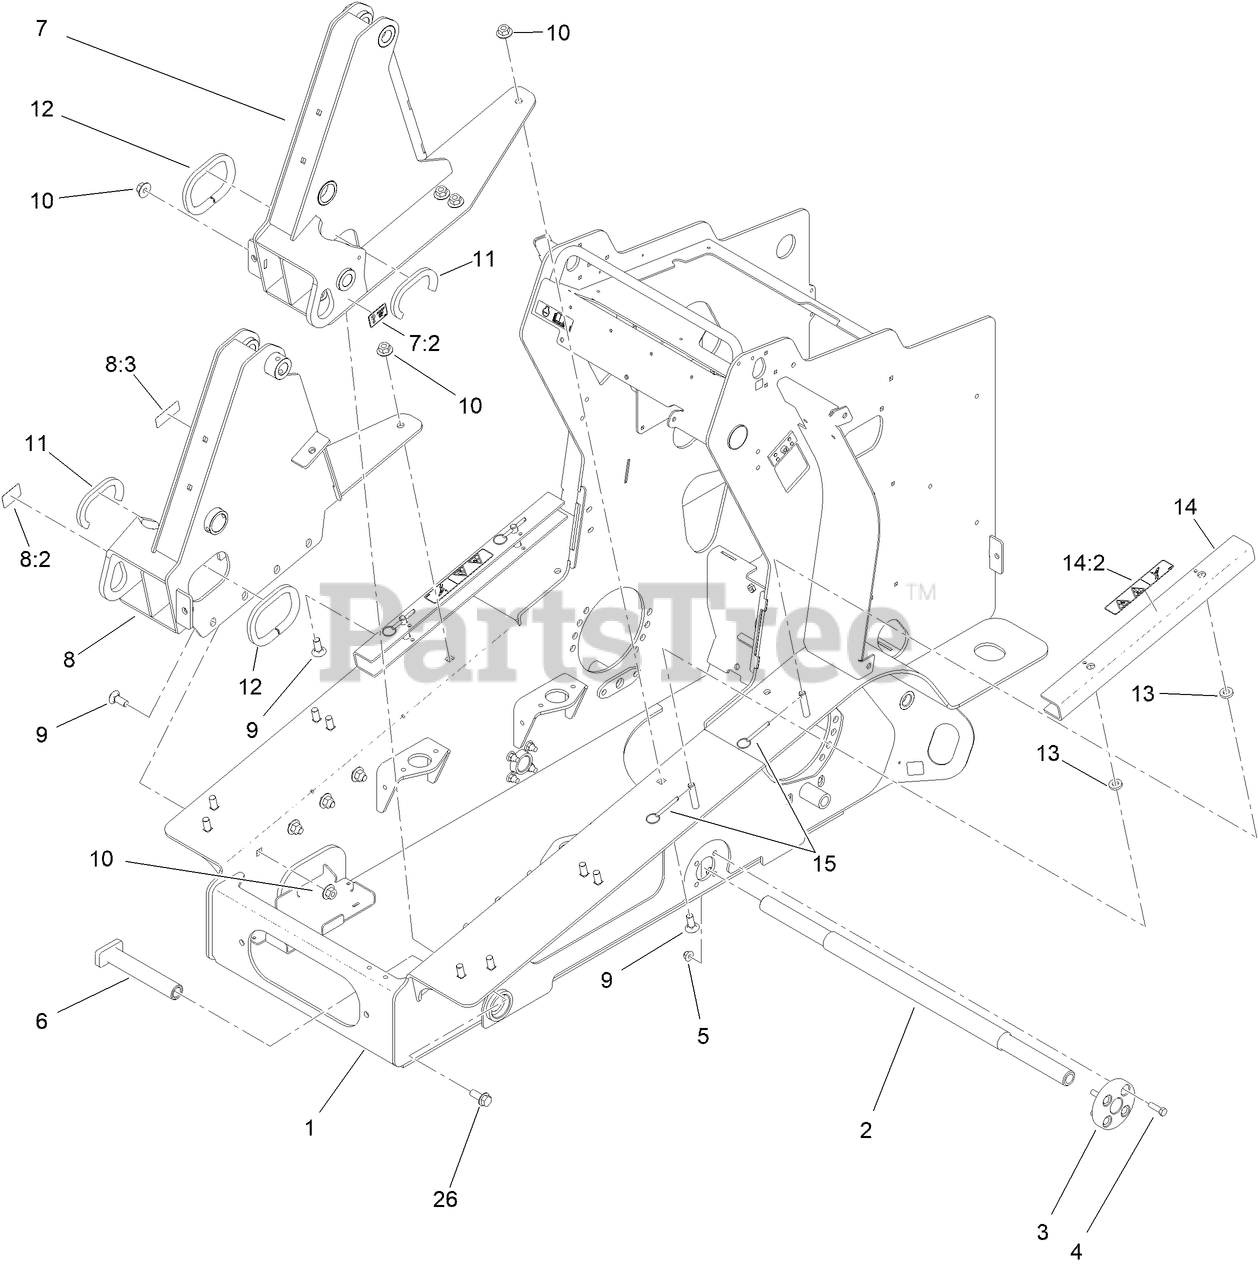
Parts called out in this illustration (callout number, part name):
1	MAIN FRAME ASM
2	SHAFT-TRACK
3	HUB-SHAFT
4	SCREW-HH
5	NUT-HF, NI
6	PIN-TRACK
7	TOWER ASM-LH
7:2	DECAL-LIFT, TIE DOWN
8	TOWER ASM-RH
8:2	DECAL-LIFT, TIE DOWN
8:3	DECAL-SURFACE, HOT
9	SCREW-CARR
10	NUT-LOCK, FLANGE
11	TRIM-SEAL
12	TRIM-SEAL
13	WASHER-NEOPRENE
14	ARM-LOCKING
14:2	DECAL-DANGER
15	PIN-COTTERLESS
26	SCREW-HHF
